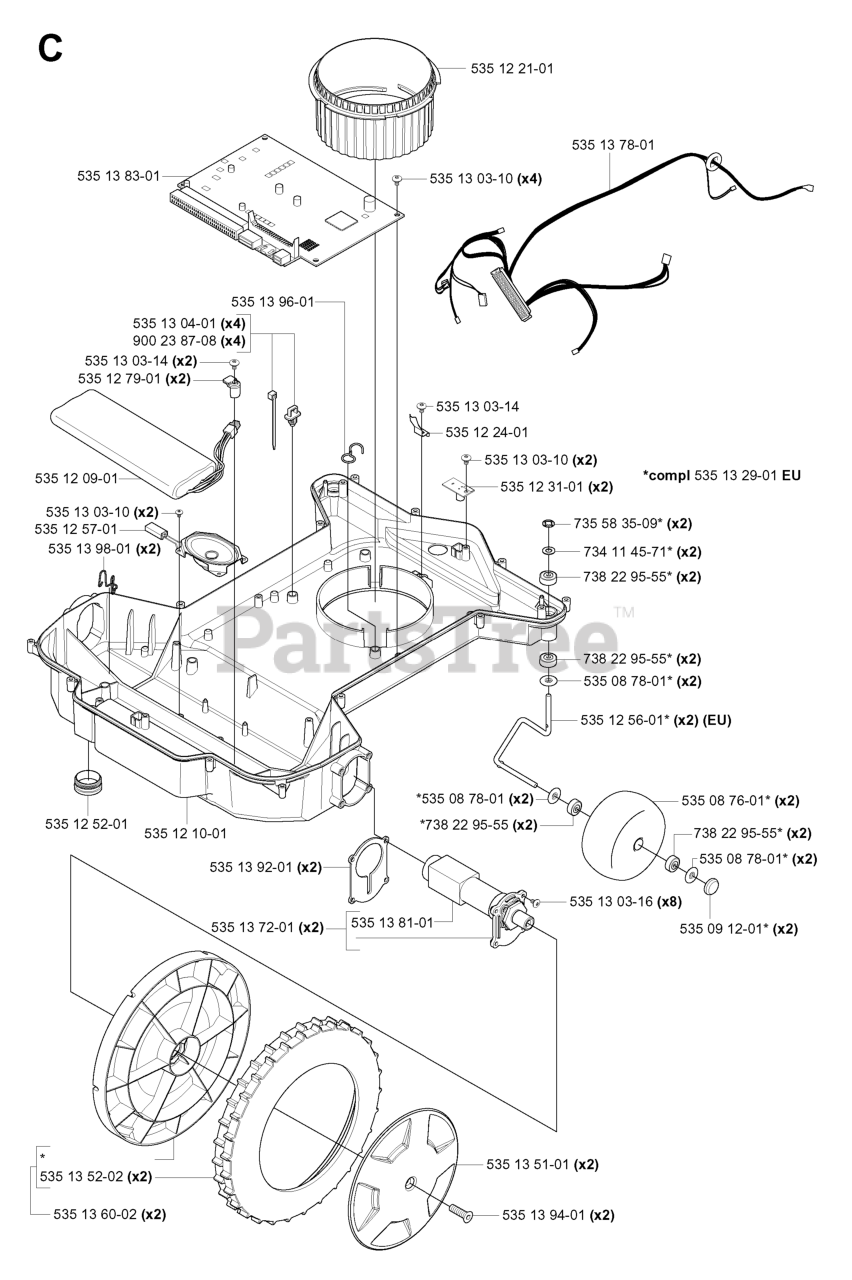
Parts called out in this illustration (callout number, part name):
1	STEERING WHEEL
2	AXLE.FRONT.CAST.MACHINE.W/ZERK
3	ZERK M
4	SPINDLE ASSY LH
5	SPINDLE ASM RH
6	THRUST WASHER
9	CAP.SPINDLE.BLACK
10	Bolt, Hex 5/8 -11 x 2 - 3/4 Gr. 5
11	TUBE, PIVOT AXLE
12	NUT-LOC,FLANGE LT
14	WASHER, LOCK 3/8
15	GRIPCO NUT
16	SHAFT ASM, STEERING
17	ROD ASSY/TIE BALL
18	DRAGLINK, BALL JOINT (3SPG1401
19	SUPPORT ASM., STEERING VGT
20	BOOT, STEERING
21	STEERING WHEEL ADAPTOR
22	BUSHING, STRG. BLK
23	SCREW.TT.#10-32X.5.3/8.FLANGE
26	CAP.WHEEL.STEERING.GREY
27	BRNG T
28	SCREW, 3/8-16X3/4
29	BEARING-FLANGE GT
31	BUSHING.NYLINER.
33	WASHER.LOCK.HVY.HLCL.SPR.5/16
34	BOLT.FIN.HEX.5/16-18X3/4
35	GEAR.ASM.SECTOR.
36	TIE ROD
38	JOINT
41	BRACKET INTERLOCK
42	Screw 5/16-18 x 1/2 Hex, Self Tapping 5/16-18 x 1/2
44	EXTENSION STEERING PREMIUM
45	Washer 13/32 x 1-1/20 x 11 Gauge
46	WASHER
47	BRACKET ASM, IDLER STATIONARY
48	SCREW 3/8-16X3/4
49	PULLEY.IDLER.FLAT.46.PR.DR.
50	NUT LOCK FLG 3/8-16 UNC
